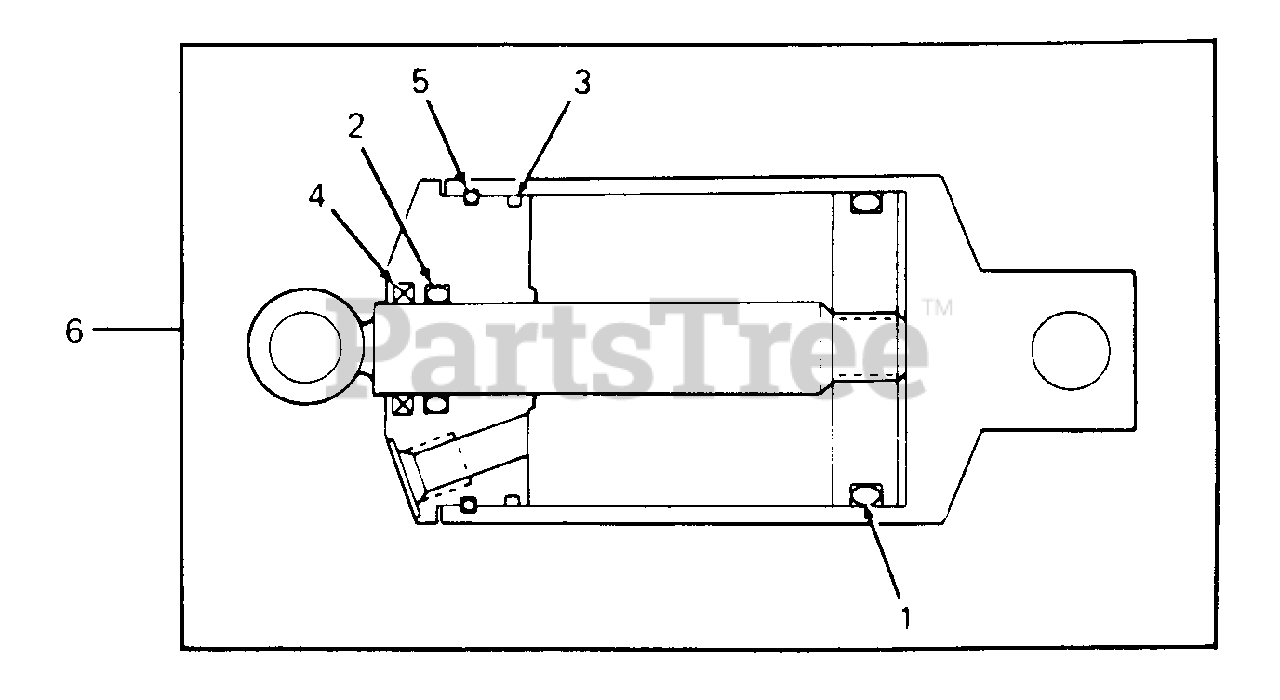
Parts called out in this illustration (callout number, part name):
4	Seal, Hydraulic Cylinder Piston Rod Wiper
5	Retainer, Hydraulic Cylinder Front Head
6	Cylinder, Hydraulic
